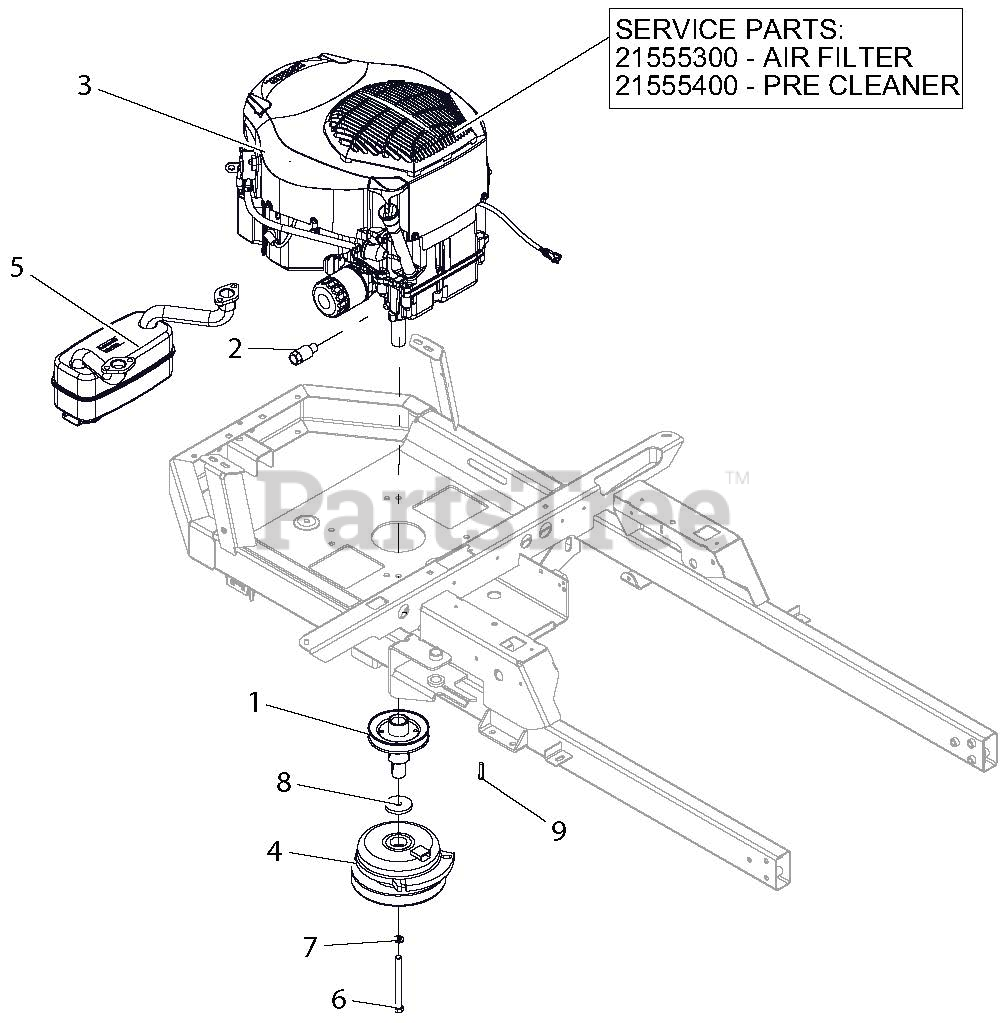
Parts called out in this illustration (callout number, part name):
1	WLDMT, DRIVE SHEAVE
2	DRAIN, OIL
3	ENGINE, KOHLER PRO25 W/SC
3	AIR FILTER
3	PRE CLEANER
4	CLUTCH, ELEC 105 FT LB MONOPOLE 6.83"
5	MUFFLER, KOHLER
6	BLT-HEX .44-20X4.50 GR8 YWZC
7	WSHR-LK .44X.109 REG YWZC
8	WSHR-FL-STL .469X2.00X.25 YWZC
9	KEY-SQ .250X.250X1.250
